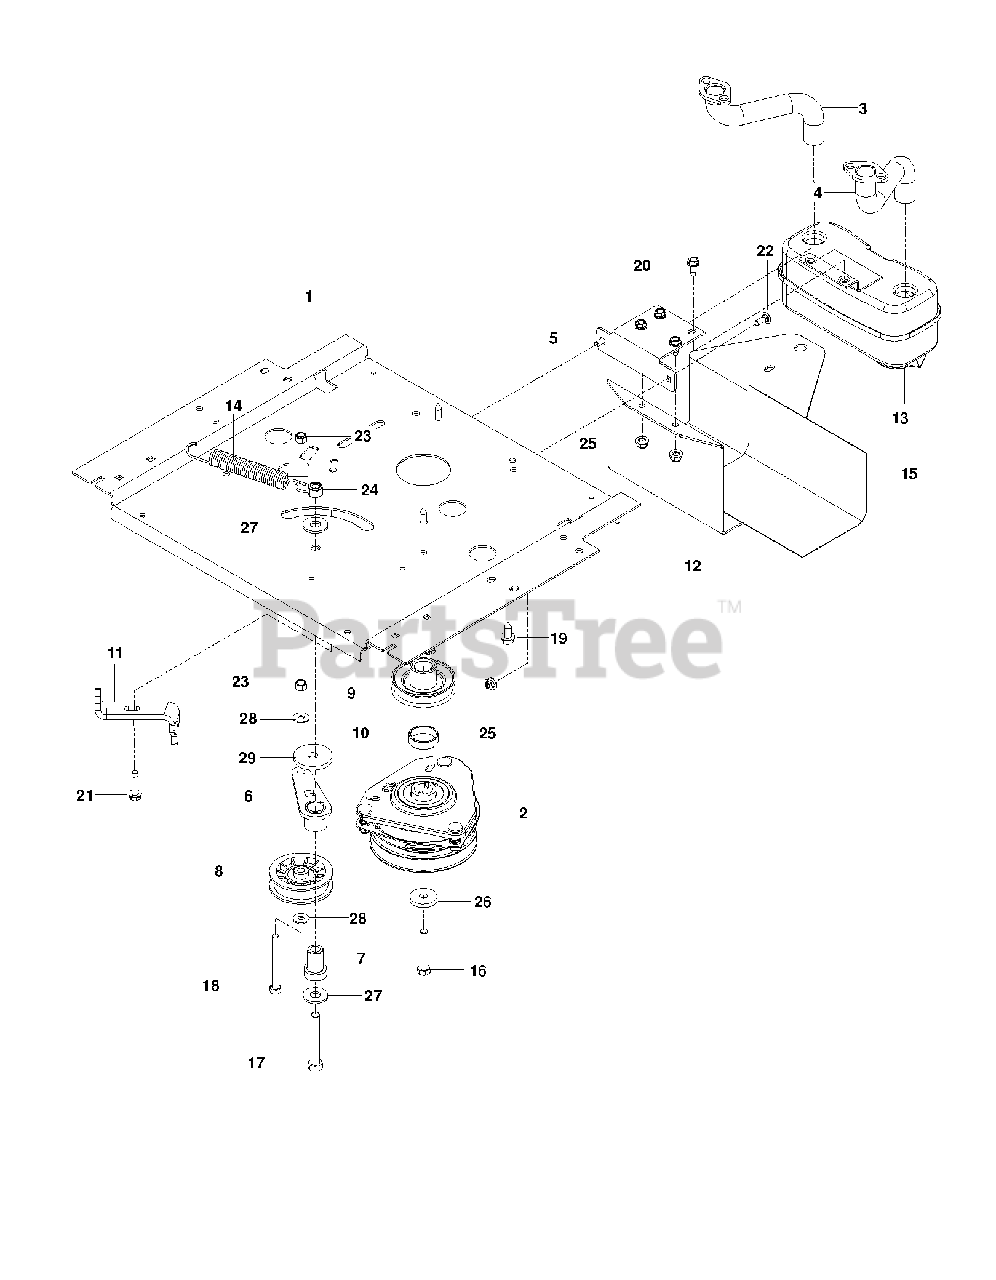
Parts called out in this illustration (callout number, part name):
2	CLUTCH.ELECTRIC.LT.48"*
3	RP.EXHAUST.TUBE.LH.BS/TWIN
4	EXHAUST.TUBE.RH.BS/TWIN
5	BRACKET, MUFFLER, BLACK
6	IDLER ARM WELDMENT
7	IDLER SPINDLE
8	PULLEY, IDLER RAKE & ZTR
9	RP PULLEY, ENGINE
10	SPACER, HUB PULLEY
11	CLUTCH STOP BLK
12	GUARD, MUFFLER, BLACK
13	MUFFLER ASM TWIN
14	SPRING, DECK DRIVE
15	HEAT SHIELD
16	HCS 7/16-20 X 2.5 GR8
17	HCS 1/2C X 3 1/4
18	HCS 3/8-16X3 1/2 GR5
19	HHFS 3/8-16 X 1.0 THD FORMING
20	BOLT 5/16-18 X 3/4
21	BOLT 3/8-16 X 1 1/2 ZINC CLEAR
22	BOLT 5/16C X 3/4" CARRIAGE
23	NUT 3/8-16 NYLOC
24	RP NUT 1/2-13 HEX NYLOC ZD
25	5/16-18 NYLOC FLANGE NUT
26	CLUTCH, WASHER
27	WASH USS FLAT 1/2
28	WASHER 5/16 FLAT
29	HEAVY WASHER
